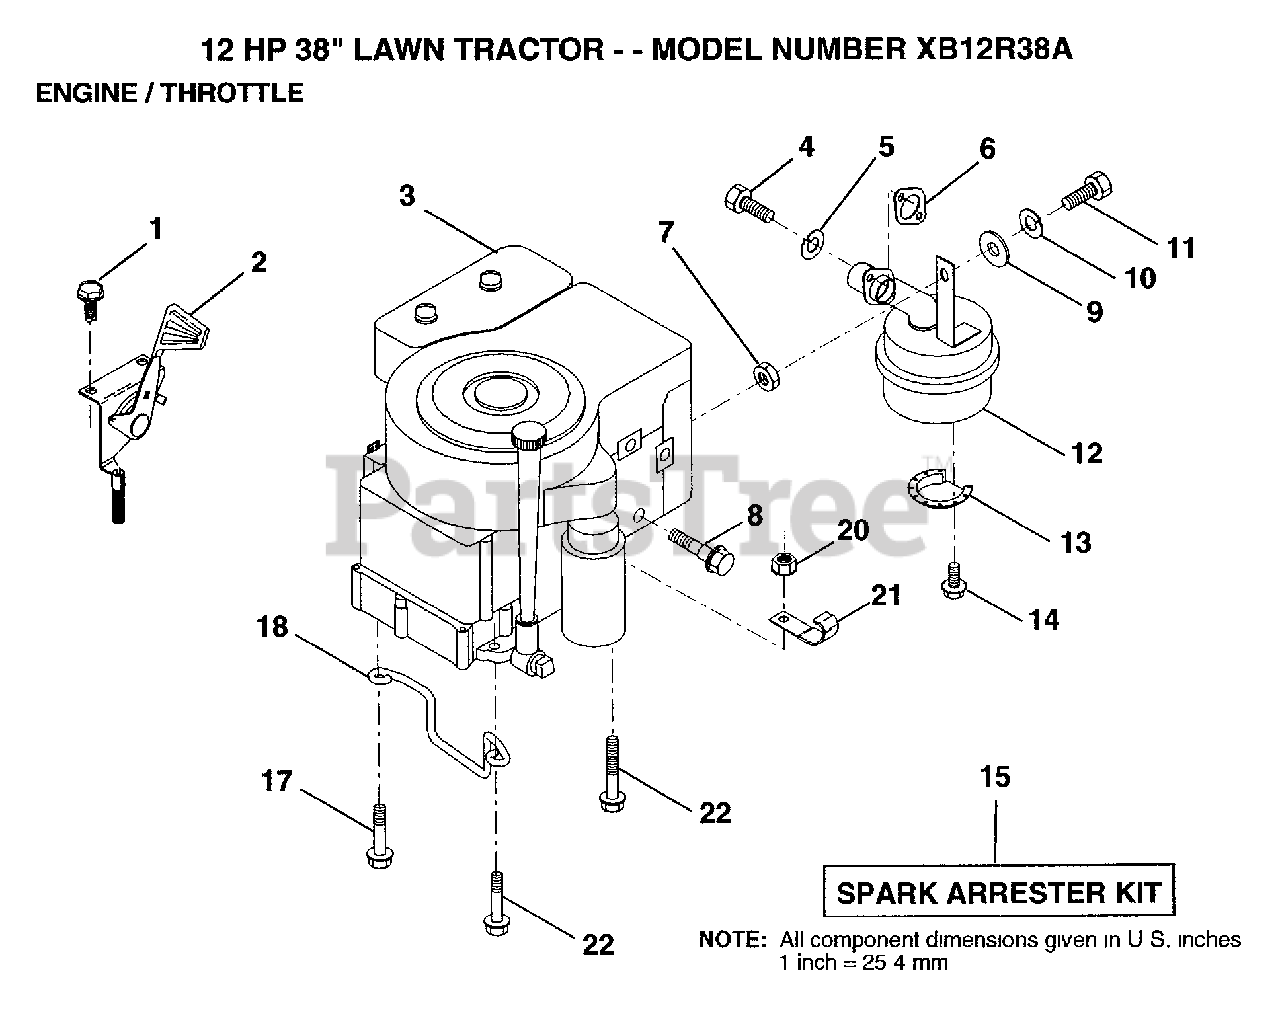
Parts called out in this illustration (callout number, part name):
1	SCREW
2	THROTTLE CONTROL
4	SCREW
5	LOCKWASHER
7	NUT.HEX.5/16-18
8	BOLT T
10	LOCKWASHER
12	MUFFLER
13	DEFLECTOR.222573
17	SCREW LT
18	"KEEPER,DR BELT GR"
20	NUT
21	CLIP T
22	SCREW LT
